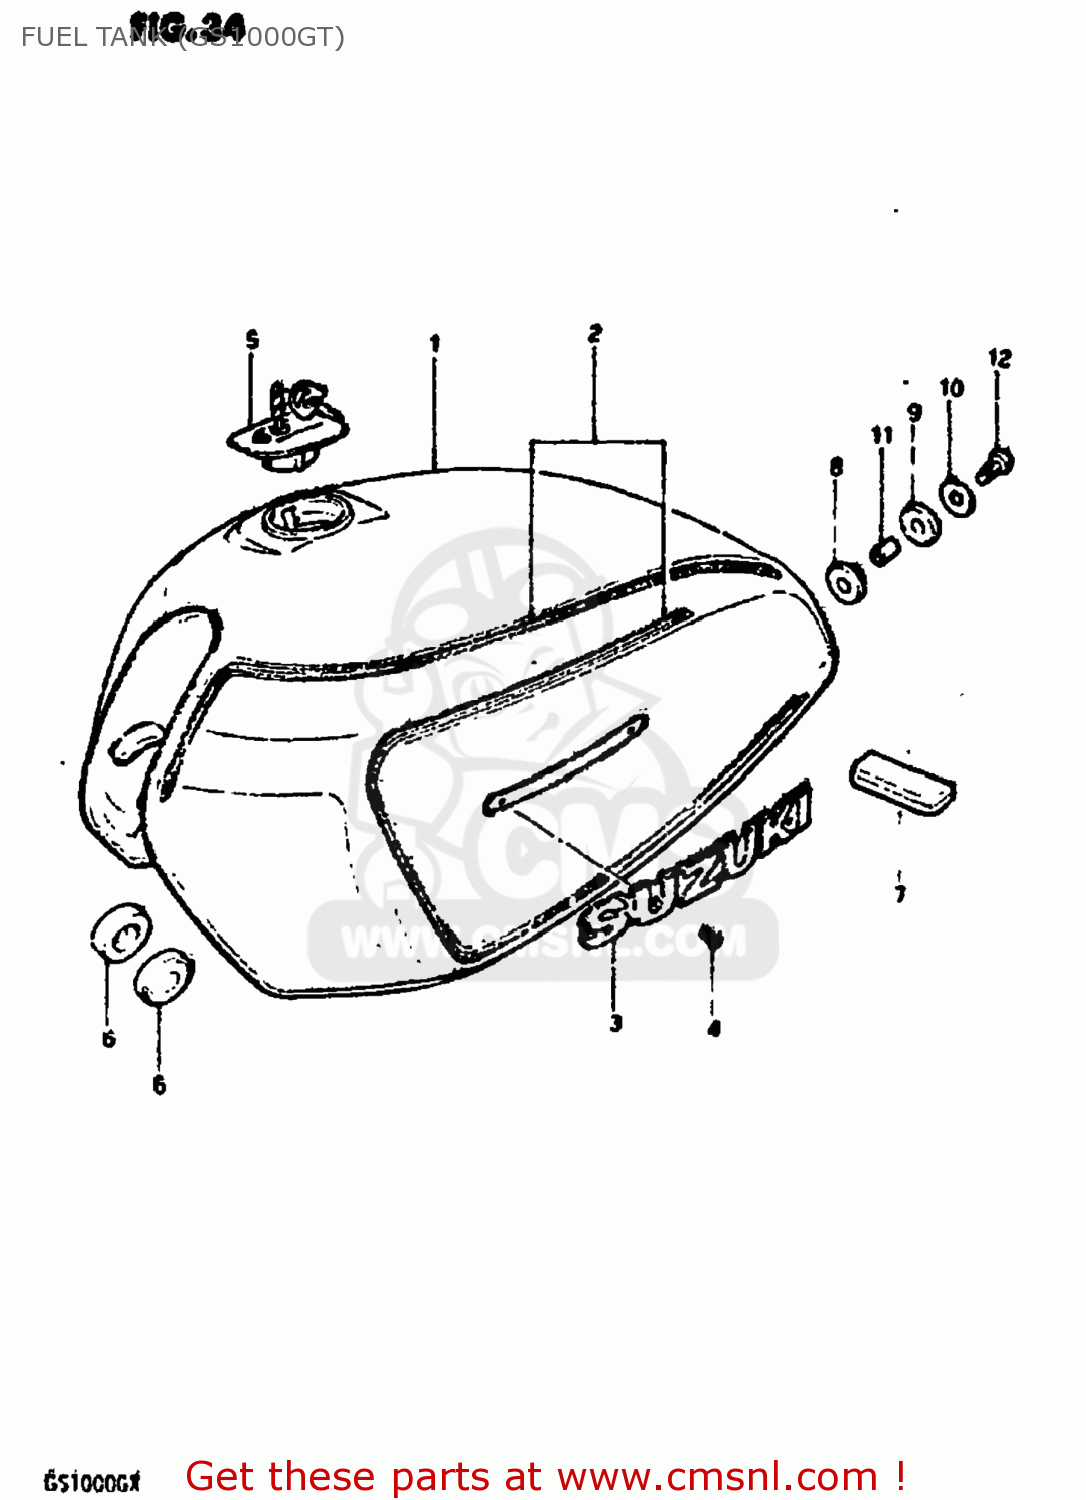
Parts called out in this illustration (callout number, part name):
1	TANK ASSEMBLY,FUEL
2	TAPE SET,FUEL TANK
3	EMBLEM,FUEL TANK
4	SCREW 3X6
5	CAP SET,FUEL TANK
6	CUSHION
7	CUSHION
8	CUSHION
9	CUSHION
10	WASHER (8.5X29X1.6)
11	SPACER(8.5X12X19)
12	BOLT (8X30)
